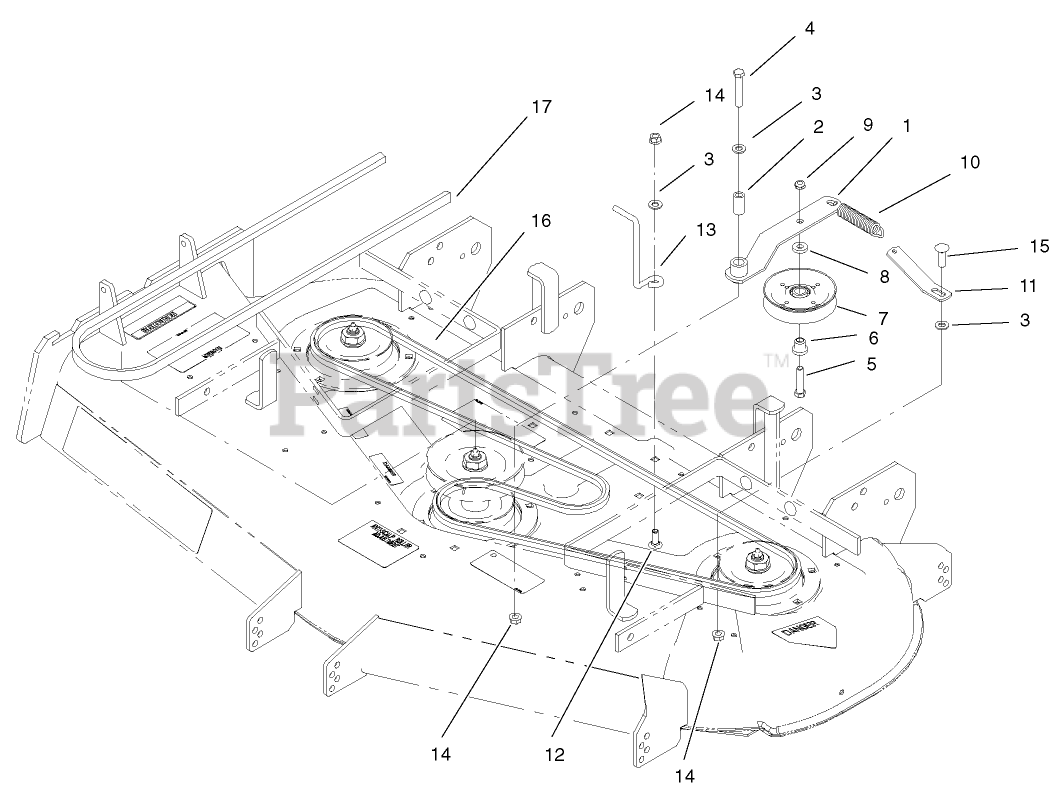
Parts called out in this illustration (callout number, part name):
1	IDLER ARM ASM
2	SLEEVE
3	WASHER-FLAT
4	SCREW-HH
5	SCREW-HH
6	BUSHING-PULLEY
7	PULLEY-IDLER
8	WASHER-FLAT
9	NUT-HEX
10	SPRING-EXTENSION
11	PLATE-SPRING
12	SCREW-CARR
13	GUIDE-BELT
14	NUT-HF
15	SCREW-CARR
16	V-BELT
17	BELT (52)
